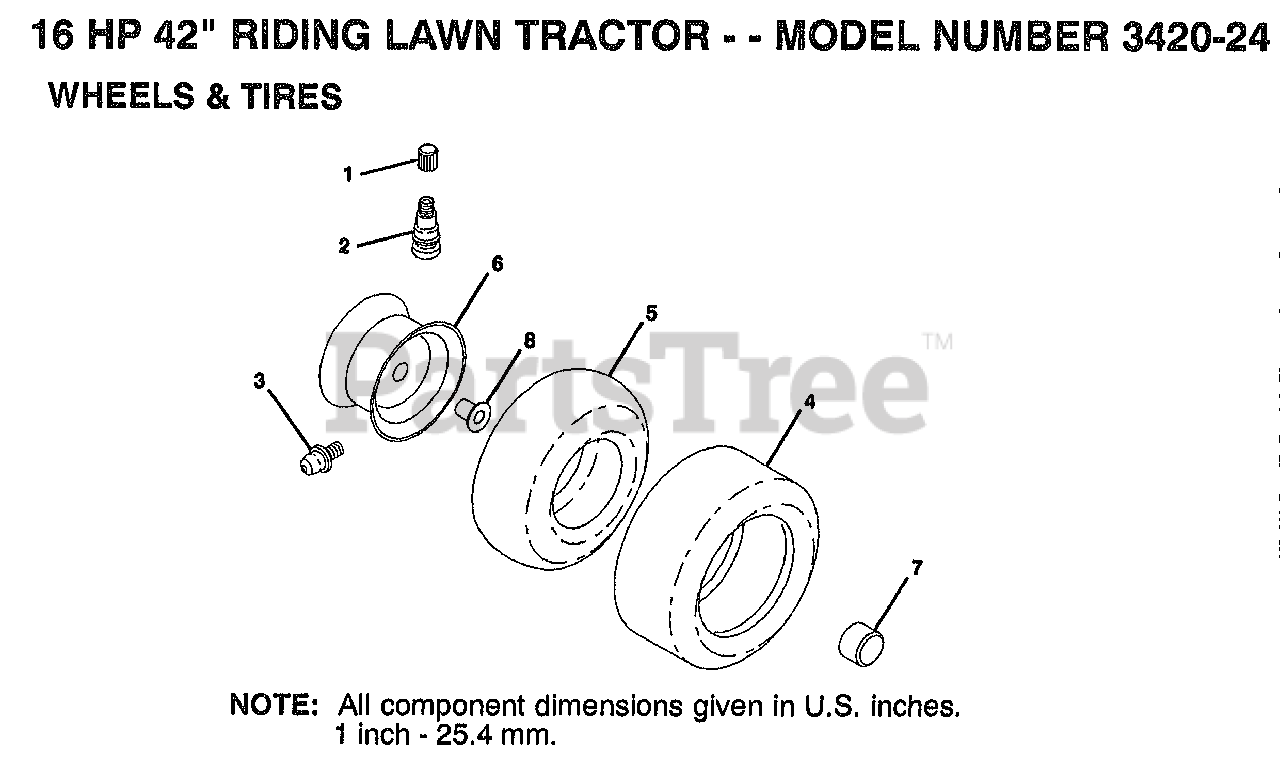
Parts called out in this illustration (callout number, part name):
1	VALVE CAP
2	VALVE STEM LT
3	FITTING LT
4	TIRE TM 15X6X6
4	TIRE TM 20X8X8
5	TUBE.5.3/4.5/6
5	TUBE.18X9.5-8
7	HUB CAP
8	"FLANGE, BEARING"
